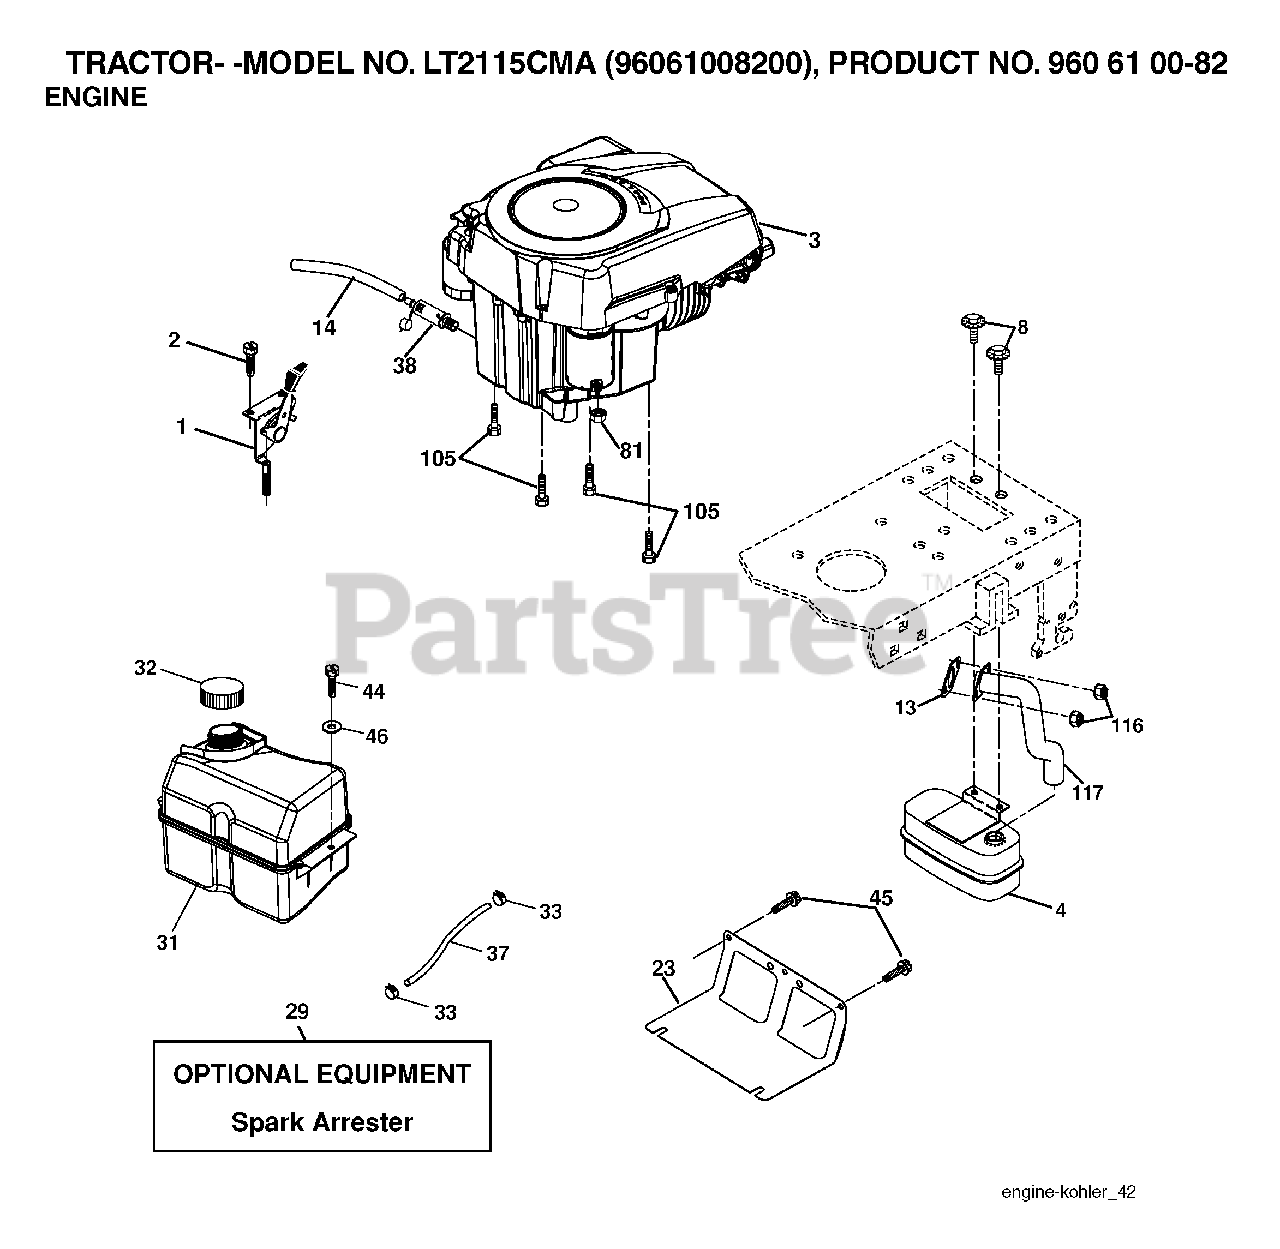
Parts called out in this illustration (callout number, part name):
1	CONTROL.THROTTLE.LT/YT
2	SCREW
4	MUFFLER.SINGLE.CYL.KOHL/B&S
8	BOLT, 5/16-18 X 1 3/4
13	GASKET ENGINE
14	TUBE, DRAIN OIL ASM.
23	SHEILD.BROWNING.DBR.GUARD
29	ARRESTER SPARK (OPTIONAL)
31	TANK FUEL
32	FUEL CAP
33	HOSE CLAMP
37	LINE.FUEL.20
38	PLUG DRAIN OIL EASY
44	SCREW HEXWSHR 1/4-20X3/4
45	SCREW, 3/8-16X3/4
81	NUT
105	SCREW 3/8-16X1
116	NUT.HEX.FLANGE.TOPLOCK
117	TUBE EXHAUST
